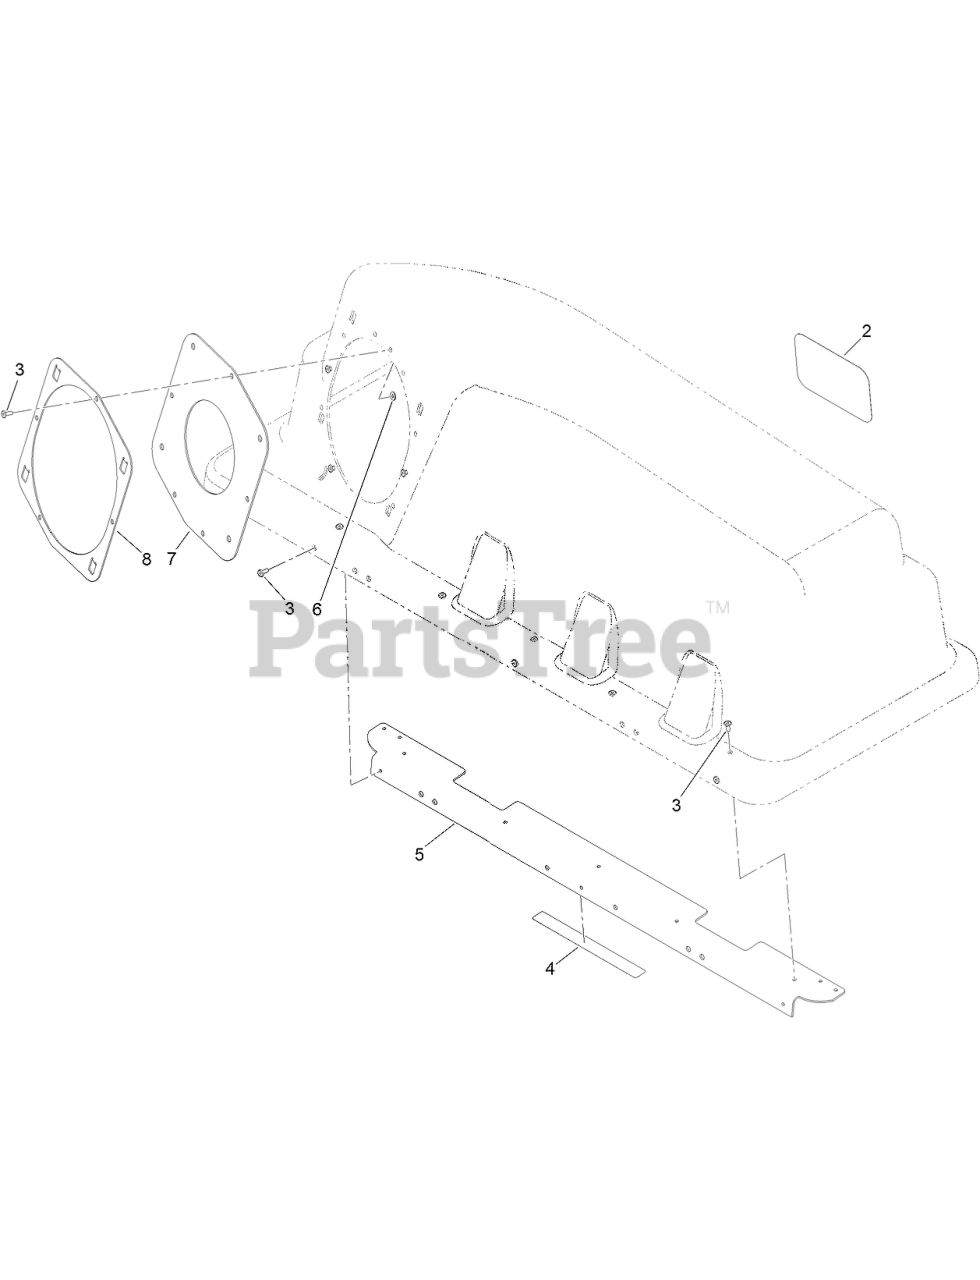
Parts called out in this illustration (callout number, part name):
2	DECAL
3	RIVET-BLIND
4	DECAL-CAUTION, BAGGER
5	STIFFENER-BAGGER, TOP
6	WASHER-FLAT
7	GASKET
8	RING-RETAINER
